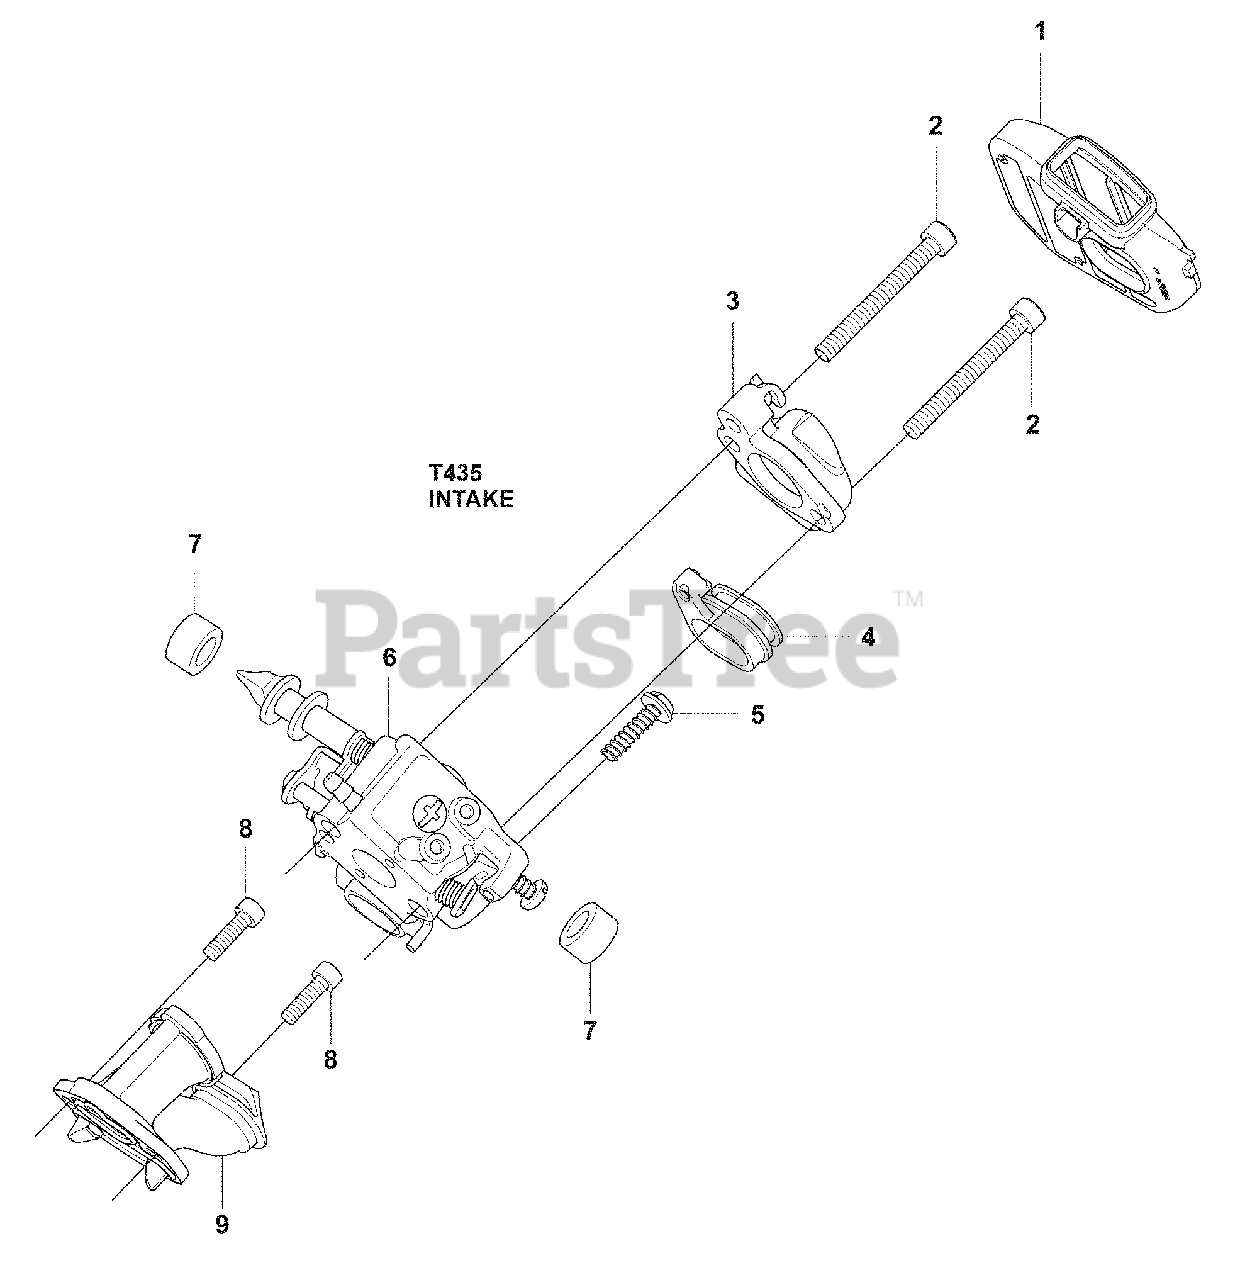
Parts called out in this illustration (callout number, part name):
1	Airfilter
2	Bolt
3	manifold
4	Seal
6	Carburettor
7	Seal
9	Inlet
